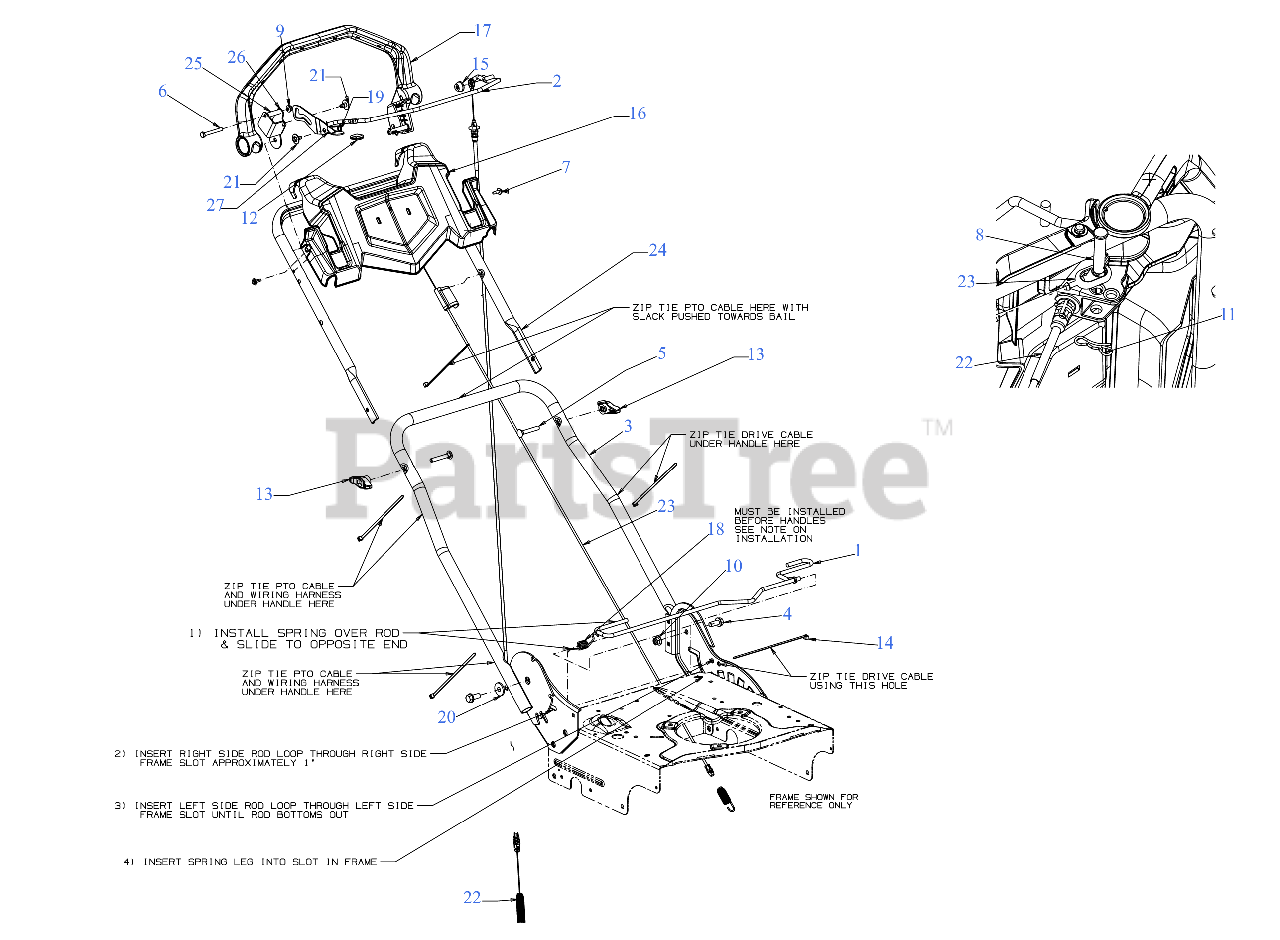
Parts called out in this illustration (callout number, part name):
1	PIVOT HANDLE ROD
3	LOWER HANDLE
4	SCREW 3/8-16 x .875 GR5
5	CARRIAGE BOLT 5/16-18 x 2.00 GR5
6	SCREW 1/4-20 x 2 GR5
7	SCREW M6-1 x .625
8	CLEVIS PIN 3/8 x 1.87
9	FLANGE LOCK NUT
11	BOW TIE COTTER PIN 1/4-5/16
12	REVERSE HANDLE GRIP
13	WING KNOB 5/16-18
14	7" CABLE TIE
15	PUSH CAP 0.3125
16	HANDLE CONSOLE
17	DRIVE HANDLE
18	TORSION SPRING .48 x .177
19	TORSION SPRING
20	SHOULDER SPACER .625 x .169
21	SHOULDER SCREW
22	CONTROL CABLE
23	DRIVE CABLE
25	SPACER:.260 x .372 x 1.420
27	LOCK OUT BRACKET
